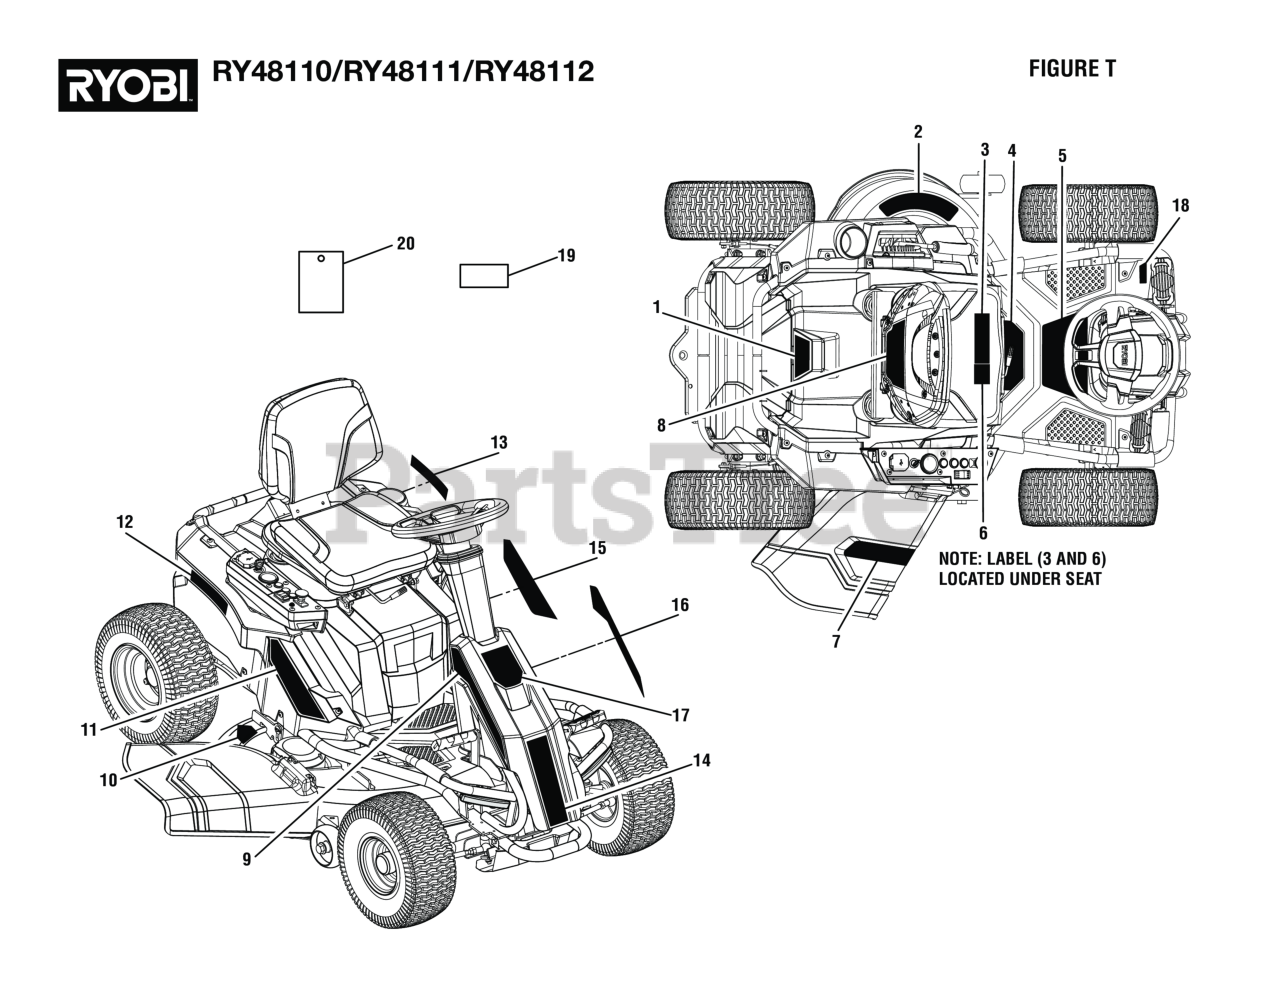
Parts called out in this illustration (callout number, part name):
1	Charging Port Label, English
1	Charging Port Label, English/French
1	Charging Port Label, Spanish
2	Deck Danger Label, English
2	Deck Danger Label, Spanish
3	Data Label (RY48111)
4	Starting Warning Label, English
4	Starting Warning Label, Spanish
5	Danger Label, English
5	Danger Label, English/French
5	Danger Label, Spanish
6	RPL Label, English
6	RPL Label, English/French
6	Danger Label (French)
7	Discharge Danger Label, English
7	Discharge Danger Label, Spanish
8	Seat Back Panel
9	Right Stripes Label
10	No Hands CPSC Danger Label, English
10	No Hands CPSC Danger Label, English/French
10	No Hands CPSC Danger Label, Spanish
11	RM480e Label, Right
12	Ryobi Logo Label, Right
13	Ryobi Logo Label, Left
14	Front Column Logo Label
15	RM480e Label, Left
16	Left Stripes Label
17	Steering Column Logo Label
18	Brake Pedal Label, English
18	Brake Pedal Label, Spanish
19	Watch For Kids, Keychain Label
20	Prop 65 Hangtag
